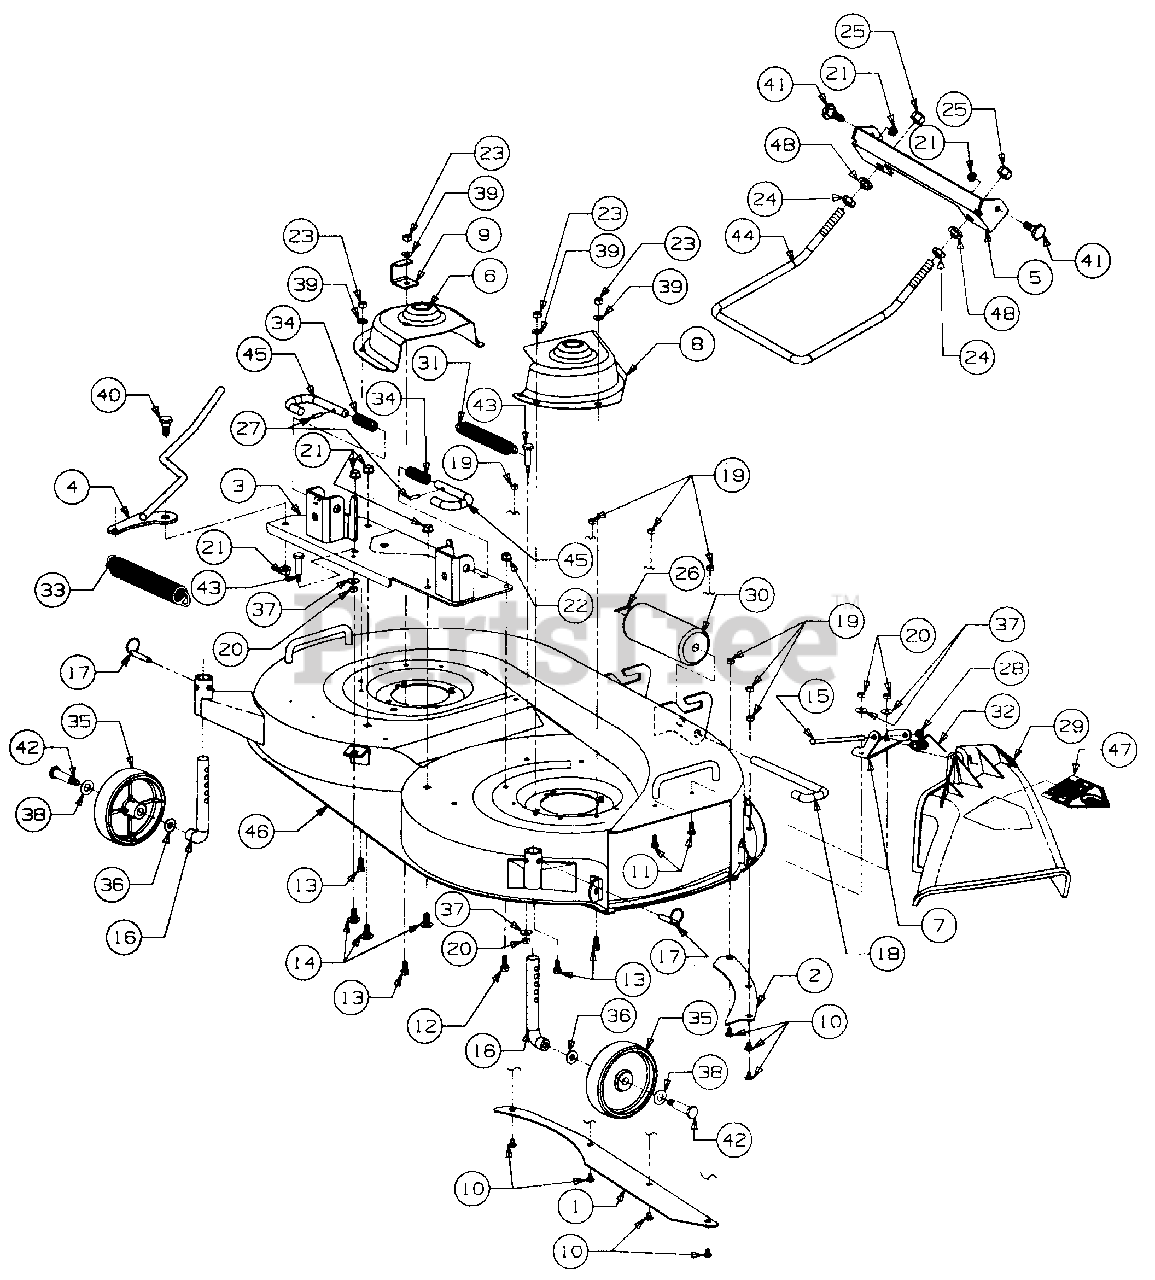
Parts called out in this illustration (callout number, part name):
1	Skirt, Extension
10	Bolt, Carriage, 1/4-20 x .50
11	Screw, Hex Cap, 1/4-20 x .62
12	Screw, Hex Cap 5/16-18 x .75 GR5
13	Screw, Hex Cutting, 5/16-18 x .6
14	Bolt, Carriage, 3/8-16 x .75 GR5
15	Pin, Hinge, .25 Dia x 6.75 Lg
16	Axle, Deck
17	Pin, Clevis w/Ball Detent
18	Pin, Roller, 1/2 Dia x 7.31 Lg
19	Nut, Hex Sems, 1/4-20
20	Nut, Hex, 1/4-20
21	Nut, Hex Flange Lock, 3/8-16
22	Nut, Hex Flange Lock, 5/16-18
23	Nut, Hex, 5/16-18 GR5
24	Nut, Hex Jam, 1/2-13 GR5
25	Nut, Hex Insert Lock, 1/2-13
26	Pin, Cotter, 1/8 x 1.0
27	Pin, Spirol Spring, 3/16 x .75
28	Cap, Speed Nut
29	Deflector Assy, Chute
31	Spring, Extension, .88 OD x 6.12
32	Spring, Torsion
33	Spring, Extension, 1.25 OD x 8.15
34	Spring, Compression
35	Wheel, Deck, 5 in. Dia
36	Washer, Bell, .380 x .88 x .062
37	Washer, Bell, .265 x .75 x .062
38	Washer, Flat, .510 x 1.0 x .060
39	Washer, Flat, .34 x .68 x .062
40	Bolt, Shoulder, .498 Dia x .340 Lg
41	Bolt, Shoulder, .50 Dia x .434 Lg
42	Bolt, Shoulder, .498 Dia x 1.64 Lg
43	Bolt, Shoulder, .375 Dia x 1.16 Lg
44	Rod, Front Lift
45	Pin, Mower Support
46	Deck Assy w/Graphics
47	Graphic, Danger
48	Washer, Lock, 1/2
